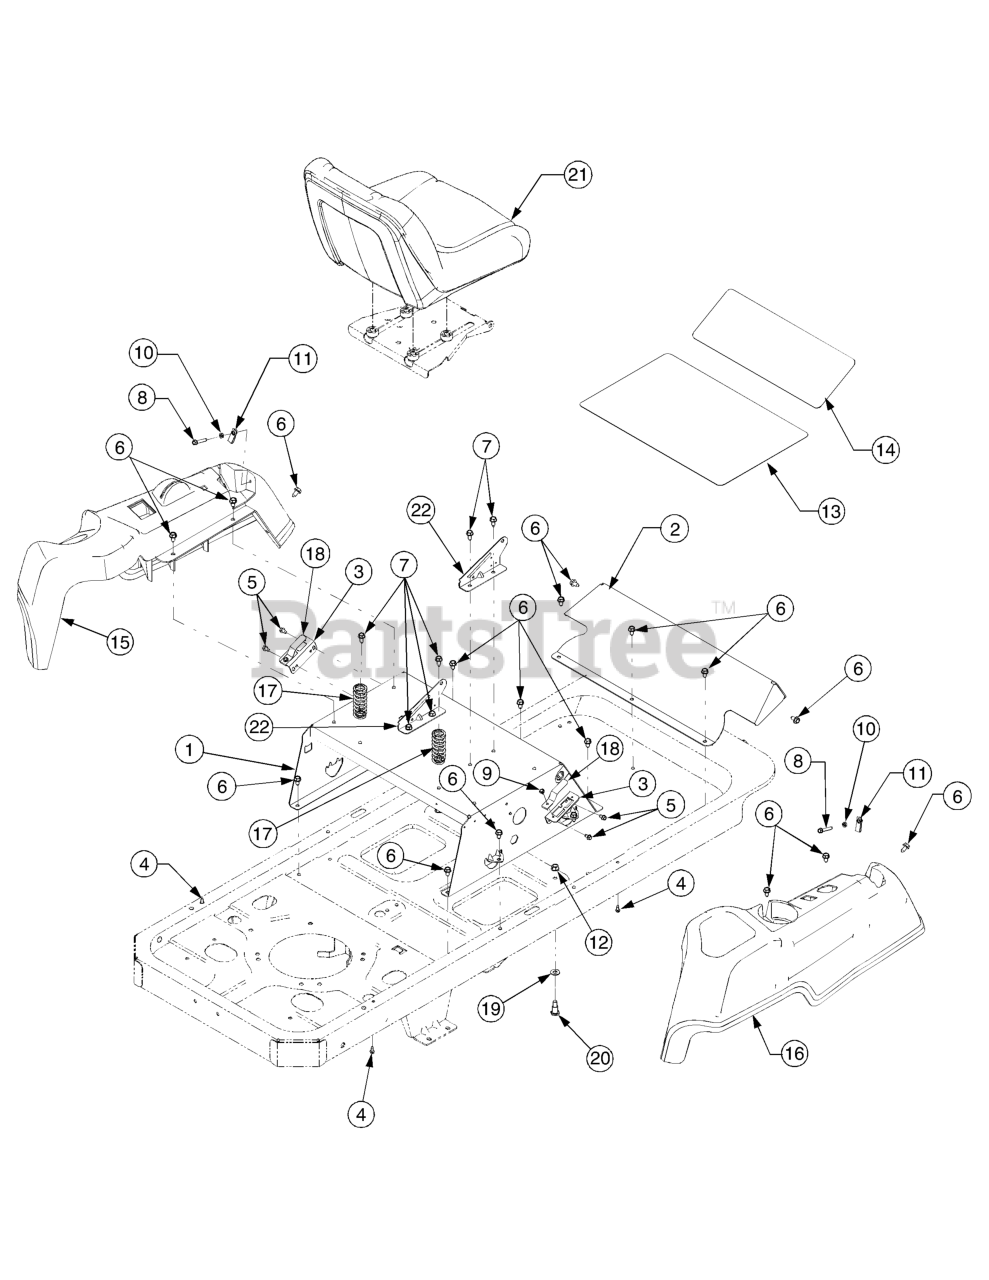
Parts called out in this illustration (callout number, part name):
1	Graphic, Warning
1	Graphic, Deck Height
4	Screw, Hex Wash. Hd Tapp #12-16 x .50
5	Screw, Hex Wash. Hd. Tapp. 1/4-20 x .5
6	Screw, Hex Wash. Hd. Tapp 5/16-18 x .625
7	Screw, Hex Wash. Hd. Tapp 5/16-12 x .75
8	Screw, Hex Wash. Hd. Tapp. 1/4-20 x 1.5
9	Screw, Hex Wash. Hd Tapp #10-16 x .375
10	Nut, Hex Jam, 1/4-20 GR2
11	Nut, U Type Speed, 1/4-20
12	Nut, Hex Flange Lock, 3/8-16 GRF
13	Pad, Abrasive Foot Plate
14	Pad, Abrasive Toe Plate
15	Console, LH
15	Graphic, Instruction
15	Graphic, Troy-Bilt
15	Graphic, Throttle Control 42"
15	Graphic, Throttle Control 50"
16	Console, RH
16	Graphic, Instruction
16	Graphic, Troy-Bilt
17	Spring, Compression, 1.28 x 3.125
18	Spring, Switch Actuator
19	Washer, Flat, .406 x .875 x .059
20	Screw, Shoulder, .50 x .685:3/8-16 ...
21	Seat
